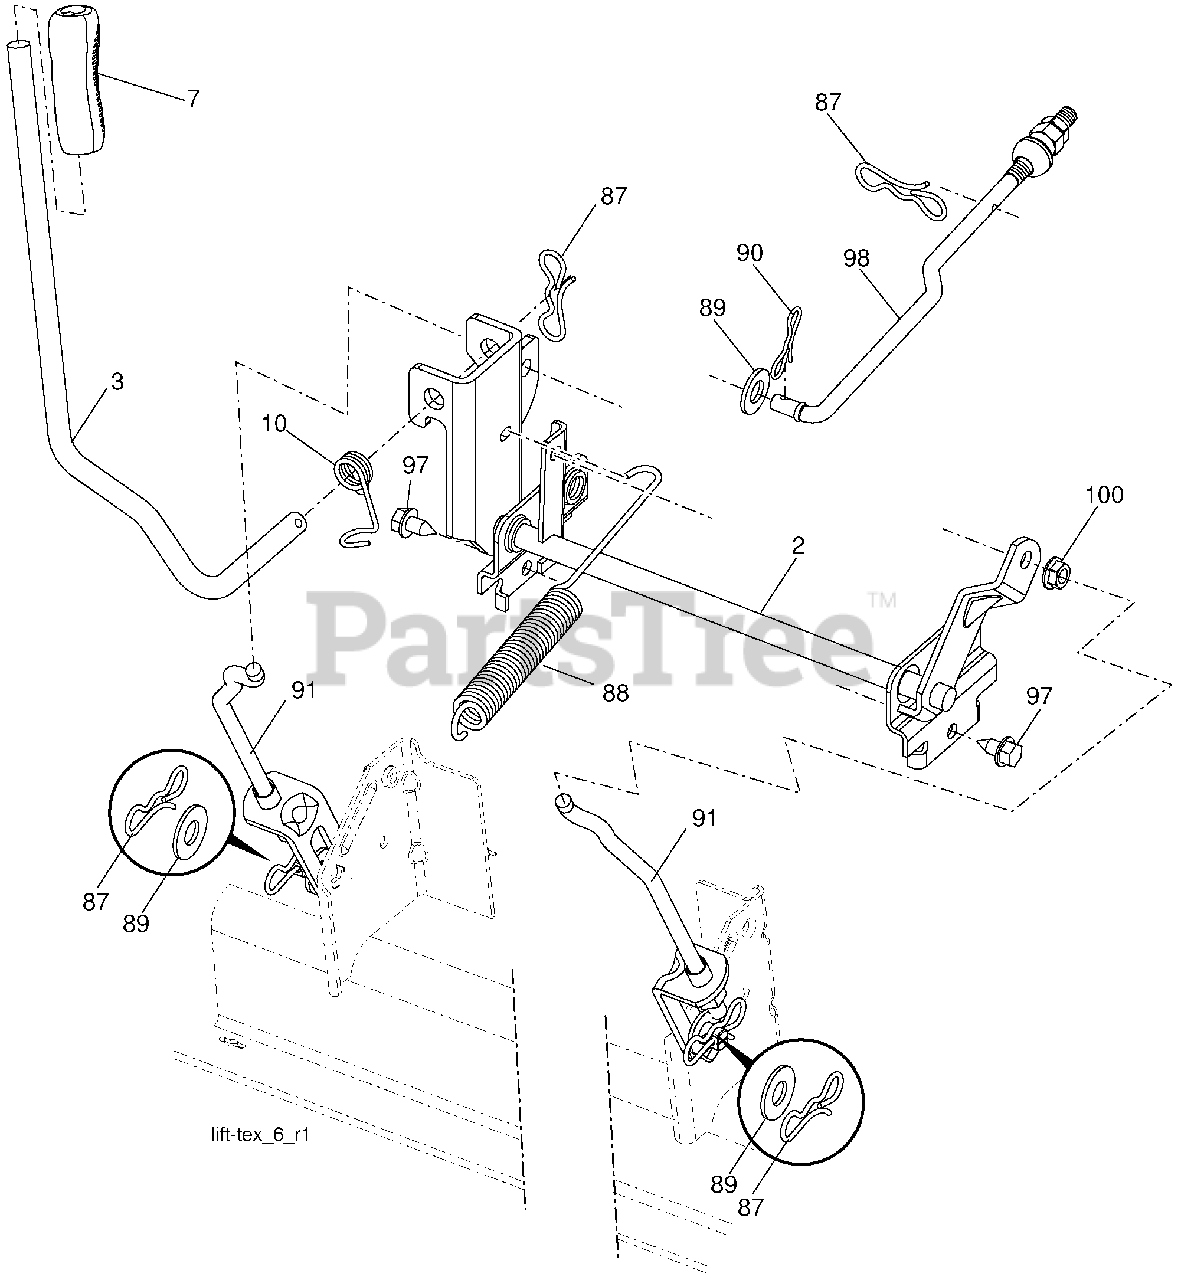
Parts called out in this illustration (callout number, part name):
2	Shaft Asm., Lift
3	Lever Asm., Lift RH
7	Grip, Lever
10	Spring Torsion
87	Pin Cotter 7/16 Bow Tie Lock
88	Spring Lift Assist
89	Washer Clear Zinc
90	Pin Cotter 5/16 Bow Tie Lock
91	Link Lift Susp Mower Rear
97	Screw 3/8-16 x .75 Smgml Tap/R.Z
98	Link Lift Susp. Front Mower
100	Nut Centerlock 3/8 -16 unc
